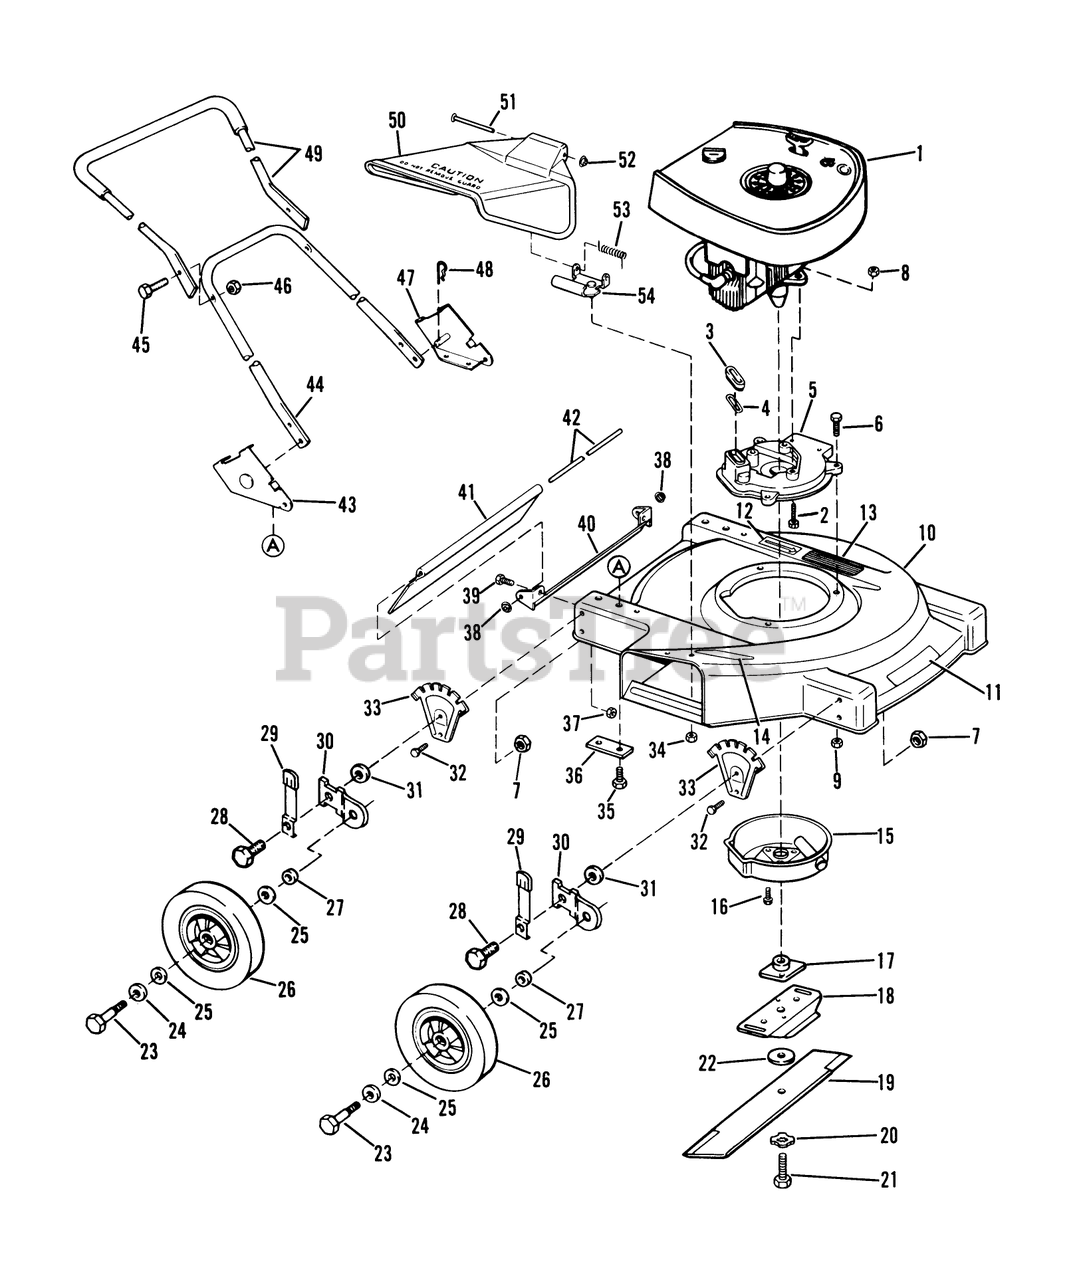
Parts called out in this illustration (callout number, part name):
3	SLEEVE
4	GASKET S
6	SCREW
7	LOCKNUT
8	NUT-LOCK F
9	NUT-LOCK F
13	PAD FOOT
16	SCREW
20	LOCKWASHER
21	BLADE BOLT
22	WASHER
23	BOLT WHEEL
24	SPACER
25	WASHER
27	WASHER WROUGHT
29	KNOB & SPRING
31	WASHER
34	LOCKNUT E
35	SCREW
37	LOCKNUT E
40	BRACKET (12)
41	TRAILING SHIELD
45	SCREW - USE 137-3042
46	LOCKNUT E
48	HAIR PIN
50	CHUTE DEFLECTOR AY
51	PIN
54	HINGE & SCREW ATA
